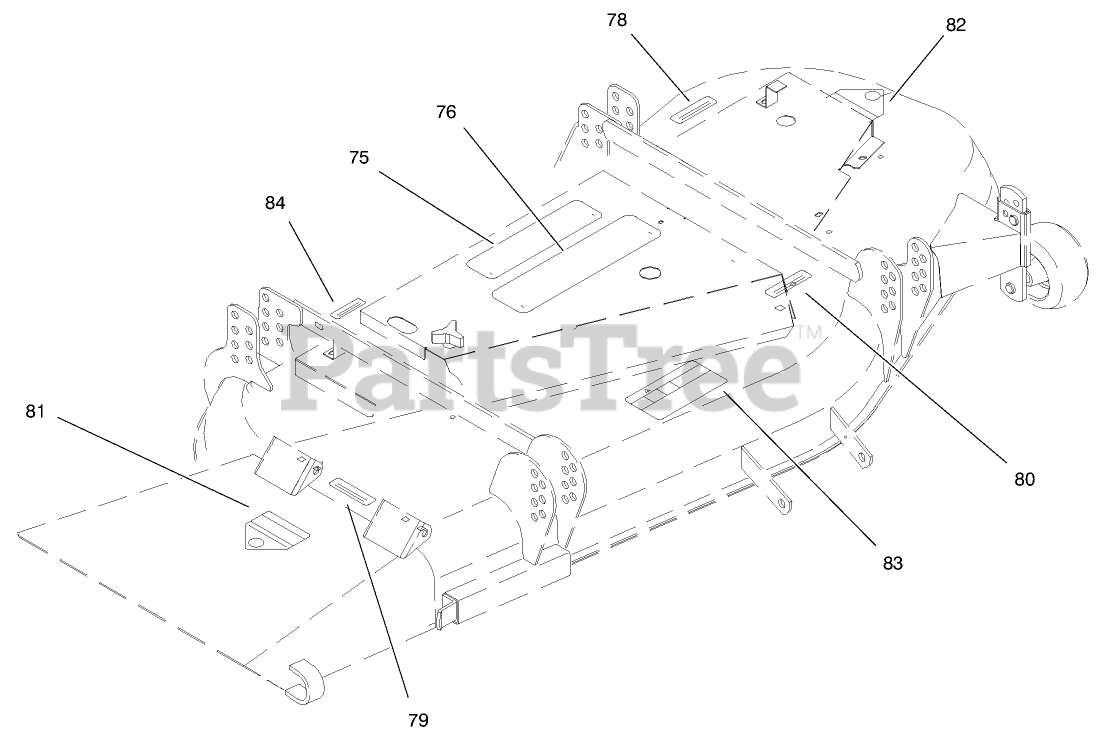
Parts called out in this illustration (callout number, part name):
75	DECAL-PROLINE
76	DECAL
78	DECAL-TORQUE
79	DECAL-DANGER
80	DECAL-DANGER
81	DECAL-DANGER
82	DECAL-DANGER
83	DECAL-DANGER, THROWN OBJECT
84	Decal-Safety
